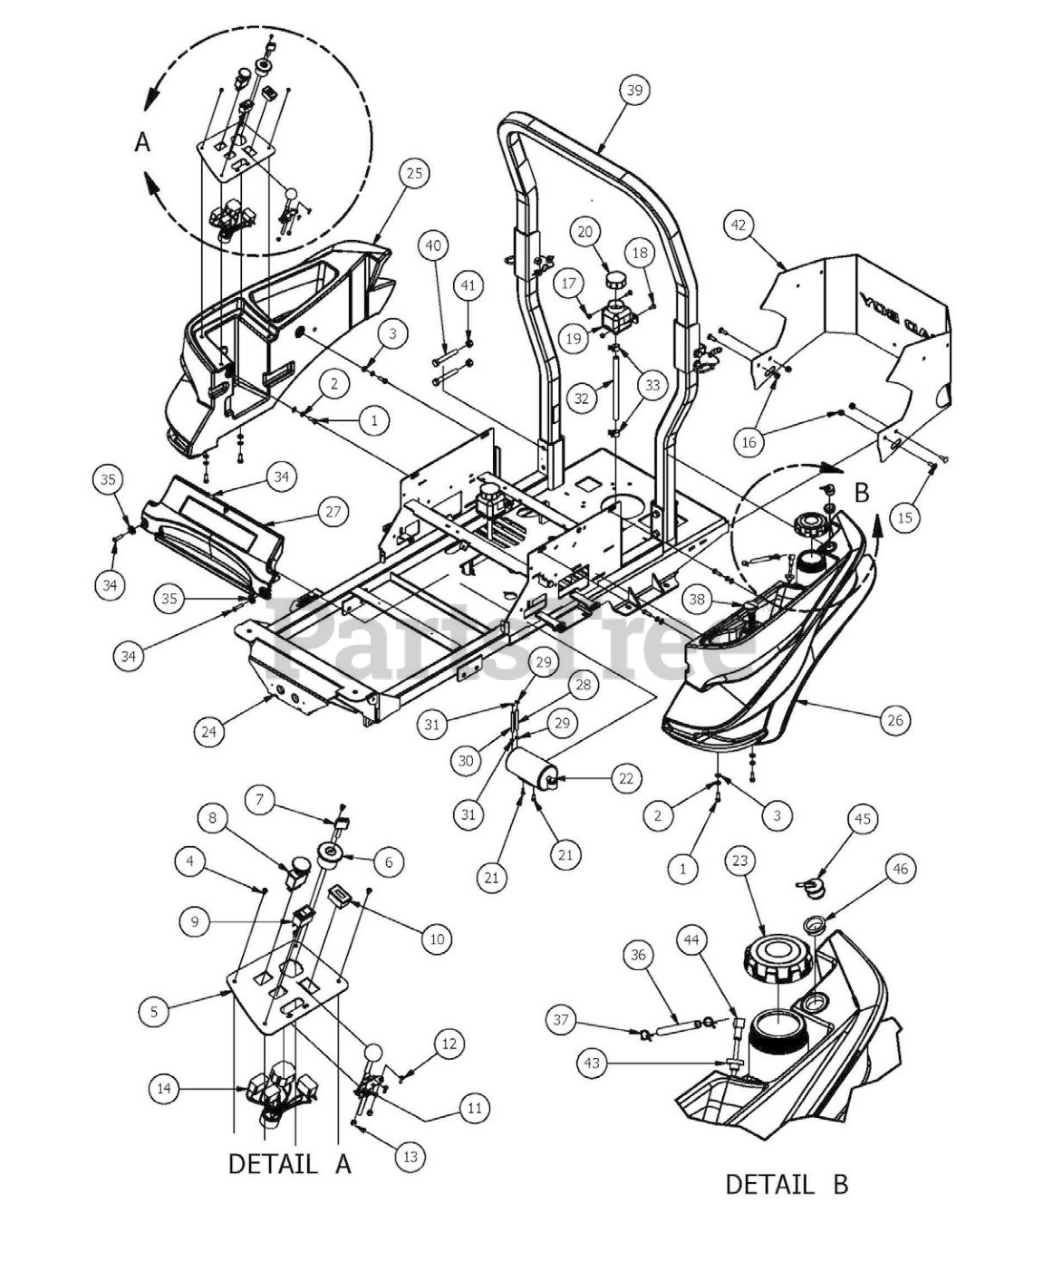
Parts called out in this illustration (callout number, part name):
1	5/16" x 1" Bolt
2	5/16" Lock Washer
3	5/16" Flat Washer
4	10-32 x 3/8" Button Socket Head Bolt
5	Control Panel
6	Ignition Switch
7	Ignition Key
8	PTO Engager
9	Rocker Deck Lift Switch 2011
10	Tachometer
11	Throttle Lever Assembly
12	10-24 X 5/8 BS Button Head Bolt
13	10-24 Nylon Insert Locknut
14	Wire Harness
15	5/16" x 1" Carriage Bolt
16	5/16-18 Nylon Flange Nut
17	1/4" Nylock Nut
18	1/4" x 3/4" Carriage Bolt
19	350ml Expansion Tank
20	Hydraulic Tank Cap
21	M6-1.0 X 16MM Hex Bolt
22	Carbon Canister
24	2017 Maverick Frame
25	Right Fuel Tank
26	Left Fuel Tank
27	Front Cover
28	1/4" Vinyl Tubing
29	1/4" Hose Clamp
30	3/16 Vinyl Tubing
31	3/16" Vinyl Hose Clamp
32	3/8" Clear Hose
33	3/8" Hose Clamp
34	5/16-18x1.5 torx cutter -Black
35	1/2" Flat Washer Flat Black
36	1/4" Fuel Line Hose
37	1/4 Fuel Hose Clamp
38	Fuel Gauge w/Grommet
40	1/2-13 x 3 1/2 GR 5 Hex Bolt
41	1/2" Center Lock Nut
42	2017 ZT Rear Plate
43	Pick-Up Grommet
45	Rollover Valve
46	Rollover Valve Grommet
